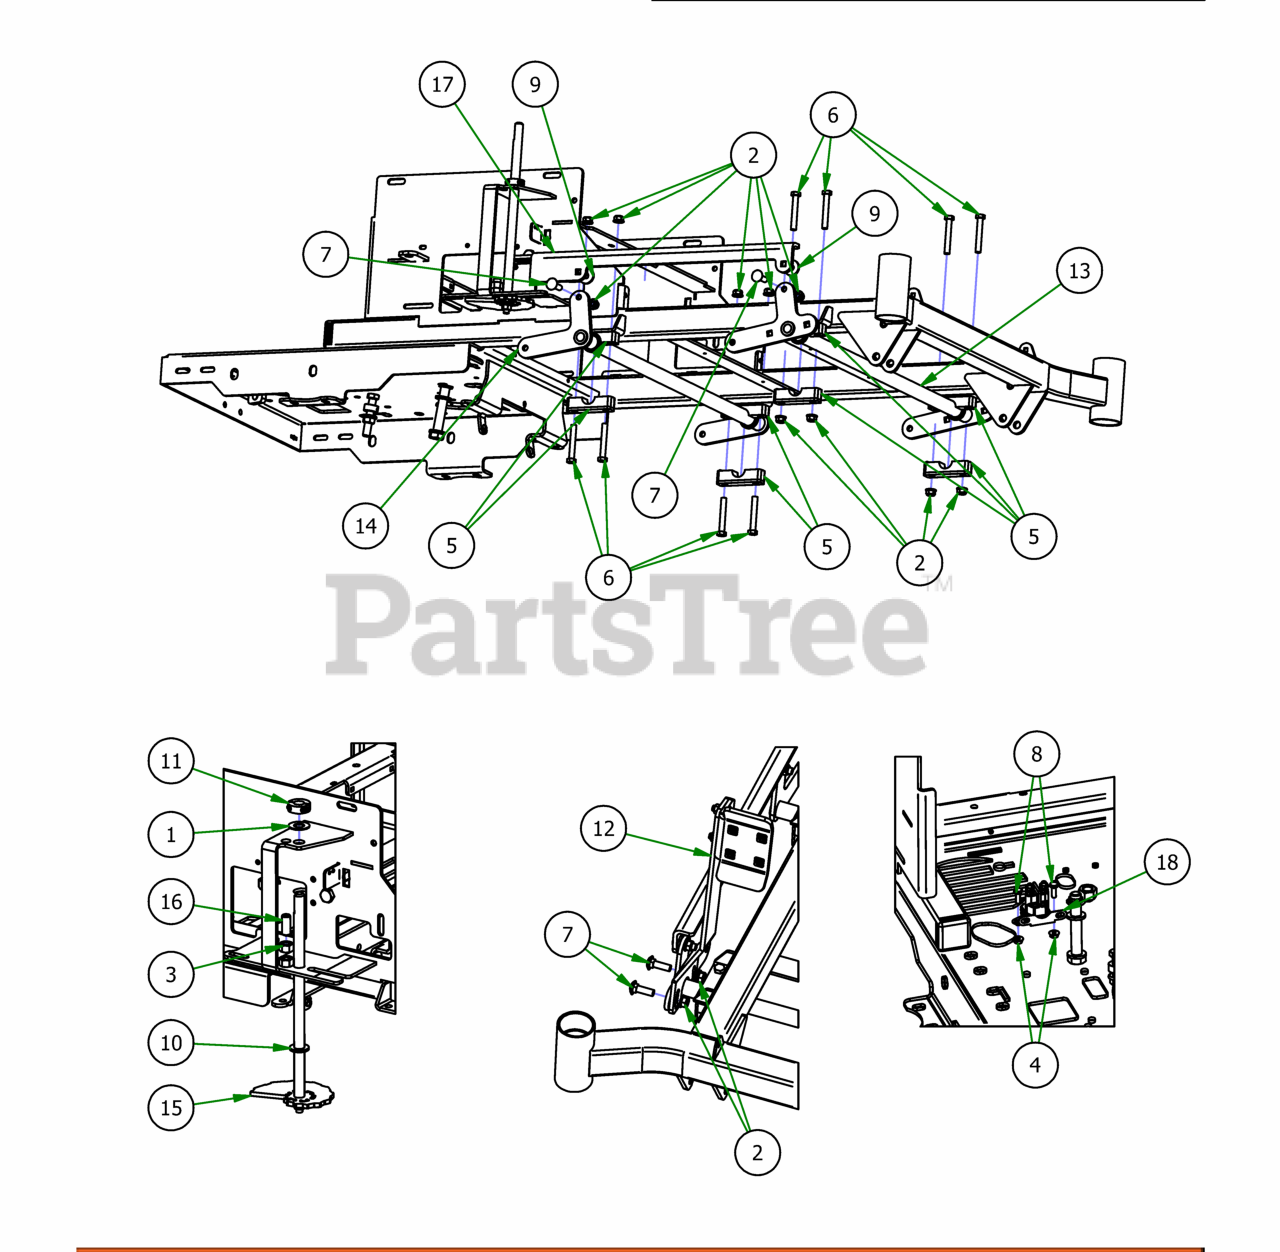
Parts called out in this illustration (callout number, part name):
1	.625 ID x 1.250 OD x .062 THK F/W Nylon
2	3/8" Nylock Flange Nut
3	1/2" Hex Nut
4	1/4-20 Hex Flange Nuts Zinc w/Serrations
5	Pillow Block Kit
6	3/8-16 x 2 1/2" Hex Bolt
7	3/8" x 1 1/4" Carriage Bolt
8	1/4" x 3/4" Hex Bolt
9	.390 ID Plastic Washer
10	.630 ID x 1.122 OD x .142 THK Plastic Washer
11	5/8" Split Collar
12	Foot Pedal Assembly
13	Actuator Bar Front- 2017 MZ/ZT
14	Actuator Bar Rear- 2017 MZ/ZT
15	Deck Height Dial Rod Assembly
16	Dial Rod Plunger
17	2017 MZ/ZT Actuator Linkage
